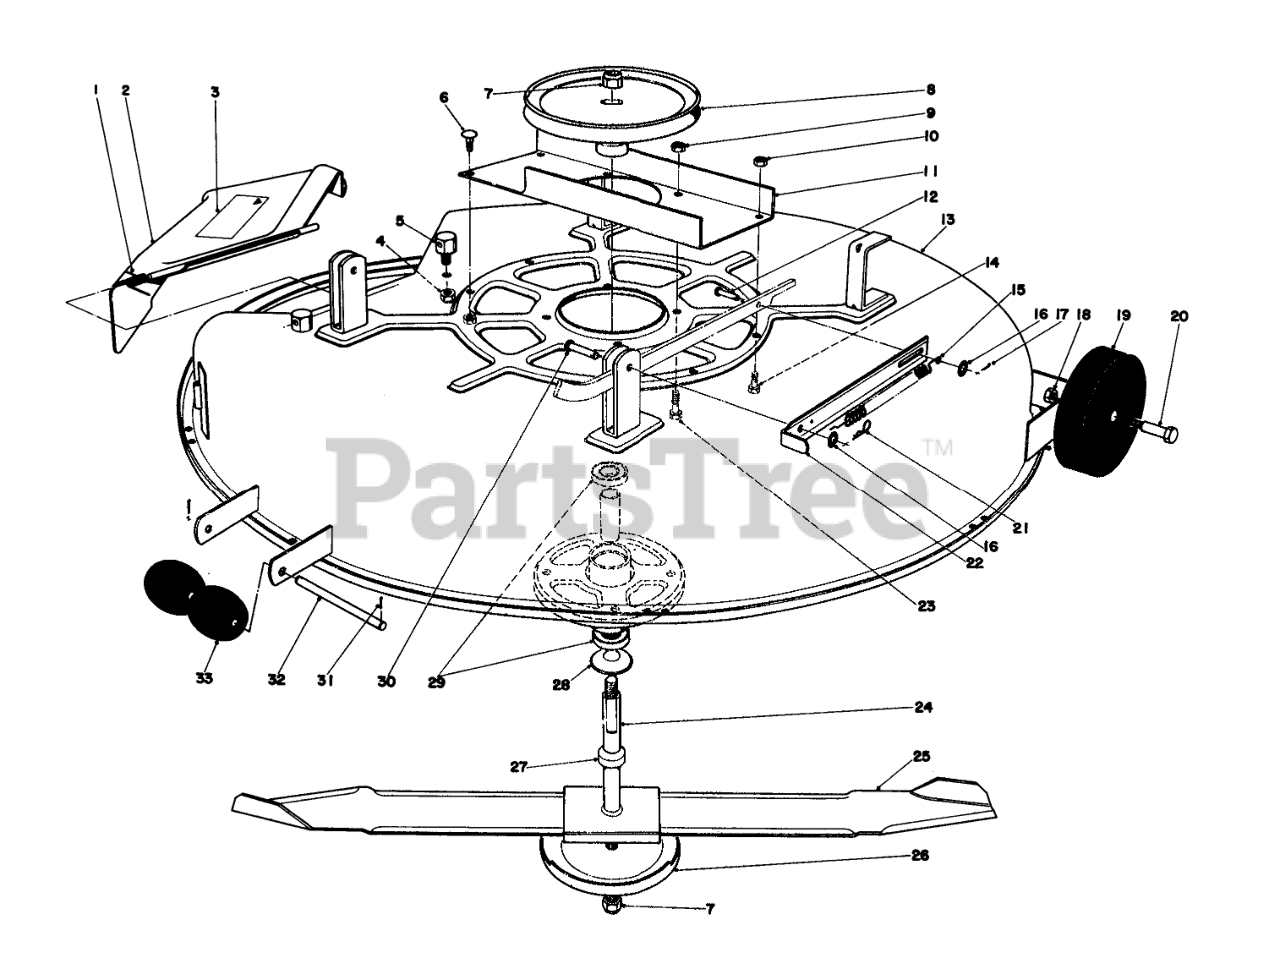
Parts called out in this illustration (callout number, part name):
1	SPRING
2	Deflector Assembly (Incl. Ref. #3)
3	Decal
4	NUT-LOCK, SIDE
5	POST-PIVOT
6	SCREW-CARR
8	PULLEY(BLADE DRIVE)
9	NUT-LOCK, CONE
11	REINFORCEMENT CHANNEL
12	PIN-CLEVIS
13	Cutter Deck
14	SCREW-HH
15	DECK TENSION SPRNG O
16	WASHER-FLAT
17	PIN-COTTER
18	Nut
19	DECK WHEEL
21	PIN-COTTER
22	Strap-Deck Spring
23	SCREW-HH
24	Spindle Assembly (Incl. Ref. #27-29)
25	Blade
26	Cup
27	SPACER
28	DUST COVER
29	BEARING
30	PIN-CLEVIS
31	PIN-COTTER
32	ROLLER SHAFT
33	Roller
